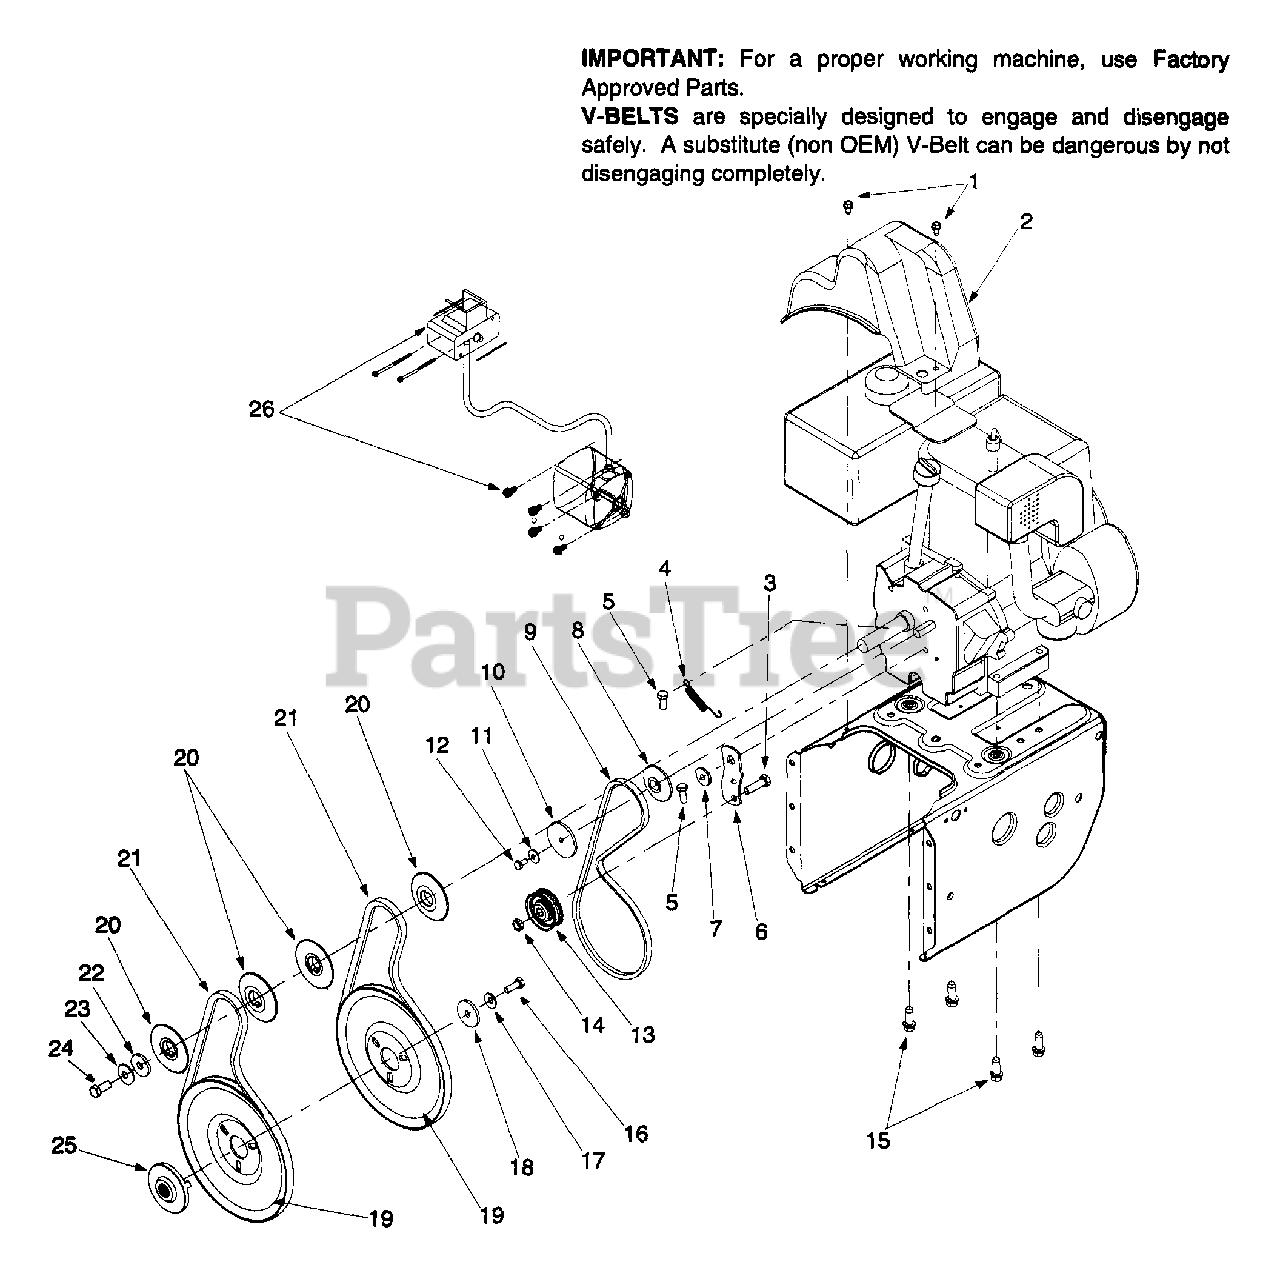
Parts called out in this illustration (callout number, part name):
1	Hex Washer Screw 1/4-20 x .50
2	Belt Cover
3	Hex Cap Screw 3/8-16 x 1.25
4	Spring Extension
5	Hex Screw 5/16-24 x .75
8	Pulley Half
10	Pulley Half
11	Bell Washer
12	Hex Cap Screw
13	Flat Idler
14	Lock Jam Nut 3/8-16
15	Hex Washer Screw 3/8-16 x 1.0
16	Hex Lock Screw 5/16-24 x .875
17	Bell Washer .340 ID x .872 OD
18	Flat Washer .341 ID x .50 OD
19	Pulley Auger
20	Pulley Half
21	V-Belt 35"
22	Flat Washer
23	Bell Washer .39 ID x 1.13 OD
24	Hex Cap Screw 3/8-24 x .875
25	Pulley Adapter
26	Electric Start
